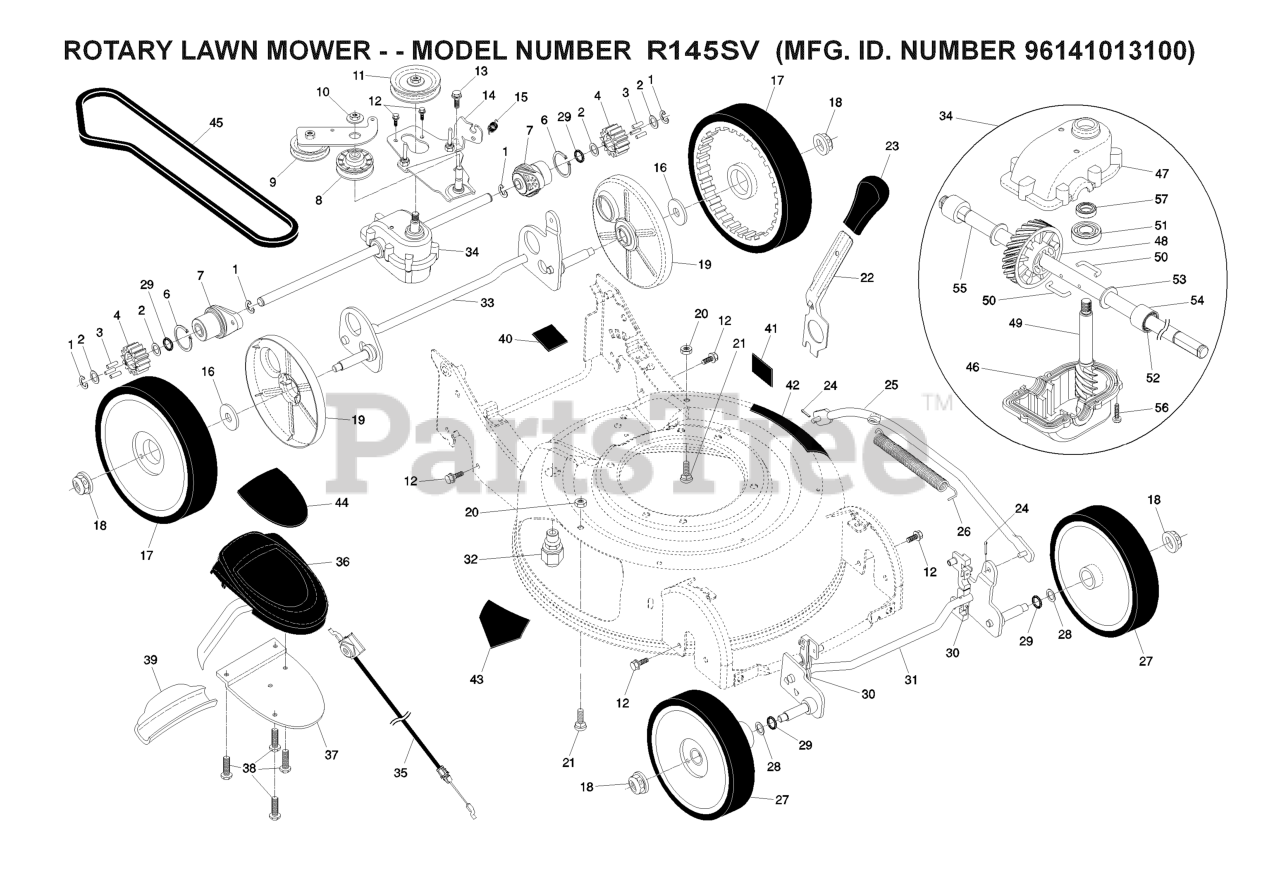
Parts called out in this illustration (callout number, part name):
1	E-RING 7/16 RE
2	WASHER
3	PAWL.DRIVE.ETCHED
4	PINION.DRIVE.WALK
6	RETAINING RING (2 2)(3 2)
8	PULLEY.IDLER.V-BELT
10	NUT
11	PULLEY.1.PIECE
13	SCREW 14-20 X 5/8
15	SPRING.RETURN
16	WASHER FLUT
17	WHEEL.8X1.75.H3SPK.RAD3.GY.BU3
18	HEX FLANGE LOCKNT
19	COVER.DUST.WHEEL
20	NUT
21	BOLT.CARRIAGE.1/4-20 X 7/8
24	RETAINER CLIP
25	KIT.ROD.LINK.REPLACE.199310
26	SPRING EXTENSION
27	WHEEL & TIRES ASSY, FRONT
28	WASHER.FLAT.1/2
29	O-RING..070X.487.NEOPRENE
30	BUSHING.FRONT.TORQUE.S
36	CONTROL.DR.HV.RGD.GRY/BLU.45CM
37	BRACKET.DRIVE.CONTROL.MOUNT.BL
38	SCREW, PHILLIPS HEAD 10 X 5/8
39	EZ WALK SNAP COVER PLATE
43	DECAL.INTERNATIONL.CUTFINGER
44	DECAL, DRIVE
46	CASE, LOWER
47	GEARCASE.HOUSING
48	GEAR.24.TOOTH.WALK.MOWER
50	WIRE, FORMED (15966)
52	SEAL.OUTPUT.SHAFT
57	SEAL INPUT SHAFT
